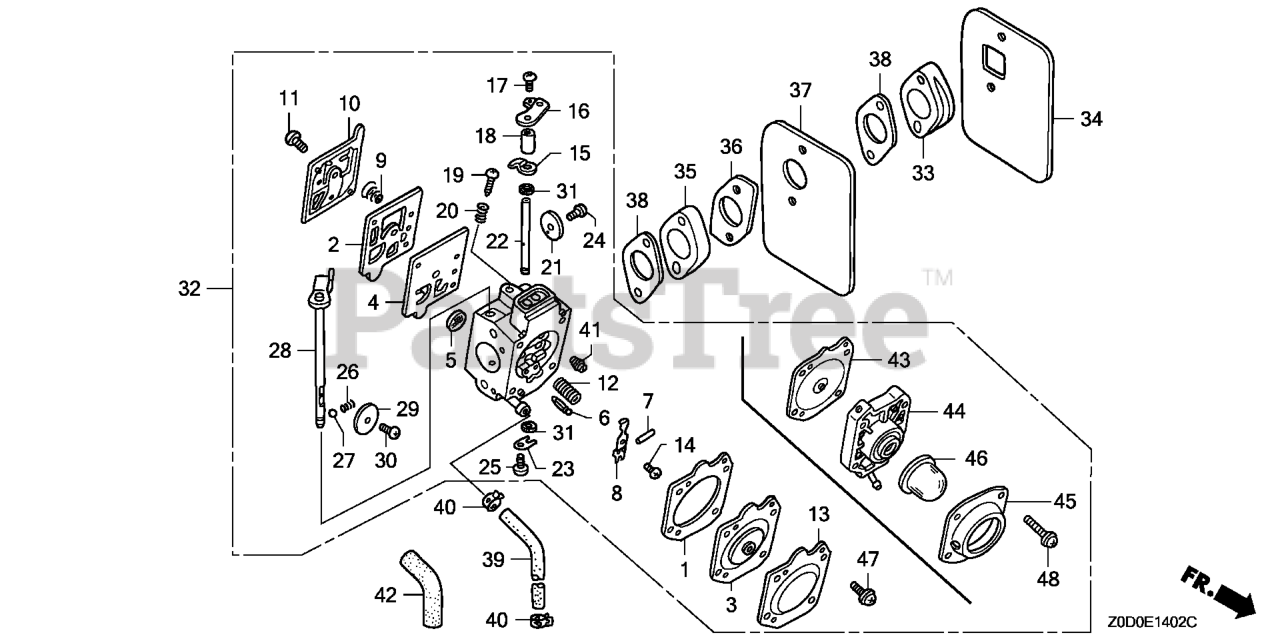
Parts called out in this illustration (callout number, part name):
1	GASKET, METERING DIAPHRAGM (CARBURETOR NO.)
2	GASKET, PUMP
3	DIAPHRAGM ASSY., METERING (CARBURETOR NO.)
4	DIAPHRAGM, PUMP
5	SCREEN, INLET (CARBURETOR NO.)
6	VALVE, INLET NEEDLE
7	PIN, METERING LEVER
8	LEVER, METERING
9	SPRING, PUMP
10	COVER, PUMP (CARBURETOR NO.)
12	SPRING (CARBURETOR NO.)
13	COVER, METERING DIAPHRAGM
14	SCREW (CARBURETOR NO.)
15	STOPPER, THROTTLE LEVER
16	LEVER, THROTTLE (CARBURETOR NO.)
17	SCREW, VALVE
18	SPACER, THROTTLE LEVER
19	SCREW, IDLE ADJUSTING (CARBURETOR NO.)
21	VALVE, THROTTLE (CARBURETOR NO.)
22	SHAFT, THROTTLE (CARBURETOR NO.)
23	CLIP, THROTTLE SHAFT
24	SCREW, VALVE
25	SCREW ASSY. (CARBURETOR NO.)
28	SHAFT ASSY., CHOKE (CARBURETOR NO.)
29	VALVE, CHOKE (CARBURETOR NO.)
32	CARBURETOR ASSY. (HDA 201F)
33	INSULATOR, CARBURETOR
34	GASKET, INSULATOR
35	INSULATOR B, CARBURETOR
36	GASKET B, INSULATOR
37	PLATE, INSULATOR
38	GASKET, CARBURETOR
39	BULK HOSE, FUEL (4.5X3000) (4.5X120)
40	CLIP, TUBE (D8.5)
41	JET (#50) (CARBURETOR NO.)
41	JET (#52) (CARBURETOR NO.)
41	JET (#54) (CARBURETOR NO.)
47	SCREW ASSY. (CARBURETOR NO.)
